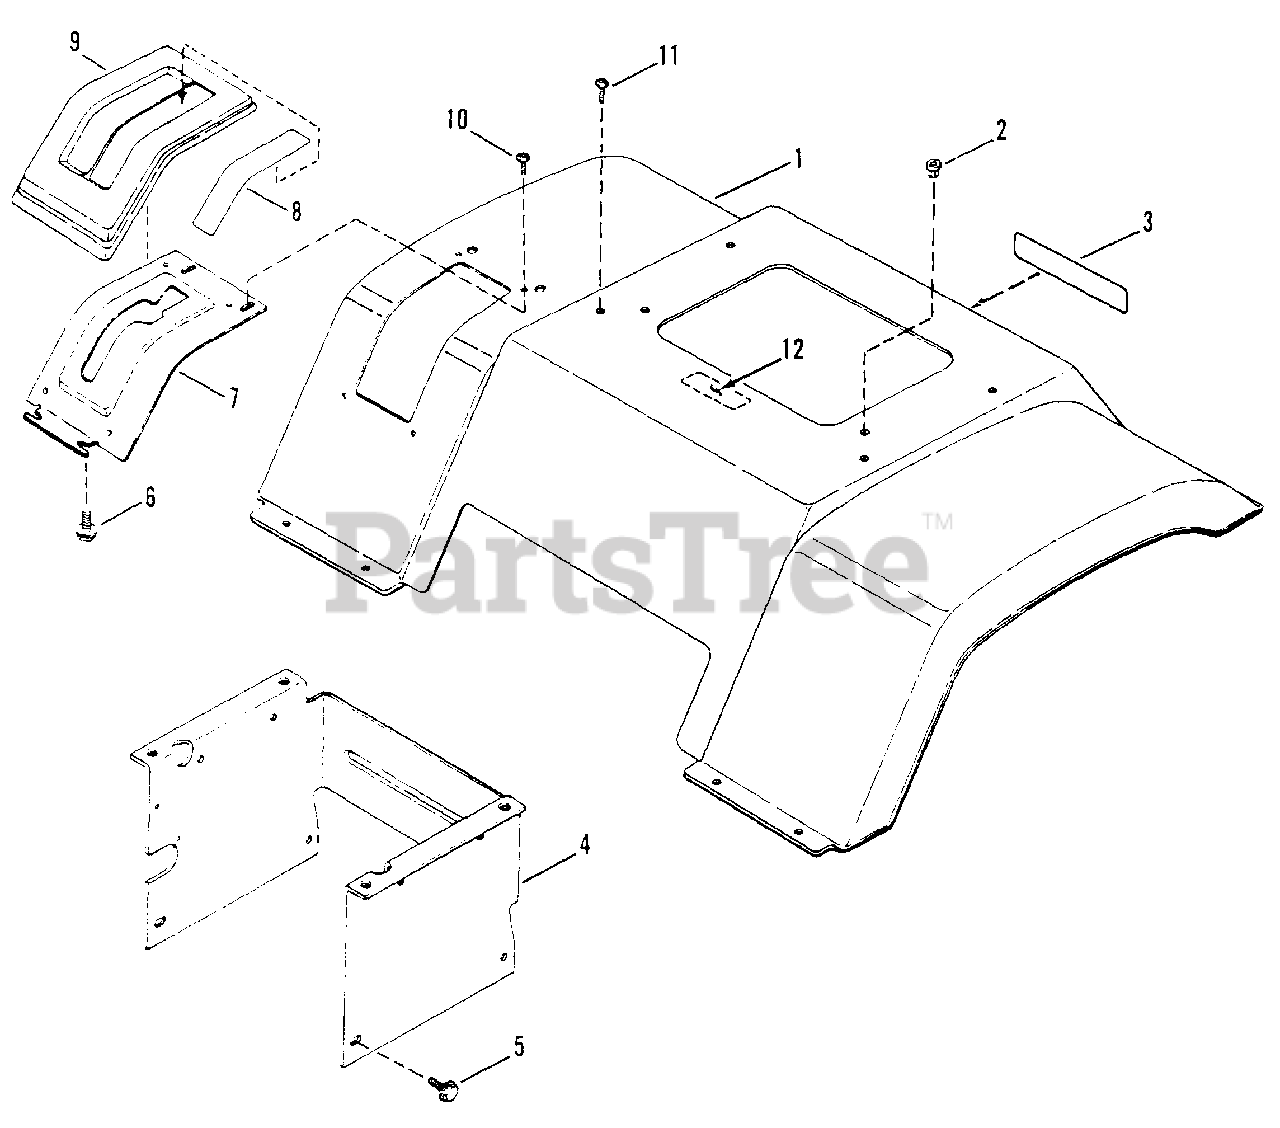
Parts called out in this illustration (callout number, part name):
1	PAN, Seat (Fender)
2	RIV-NUT, 5/16-18
3	DECAL-SNAPPER, 7.28" Molded Logo, White Letters & Stripe
3	DECAL-SNAPPER, 7.28" Molded Logo, Silver Letters, Teal Stripe
4	SUPPORT, Fender
5	SCREW, 5/16-18 x 5/8" Hex Washer Head, Self-Tapping
6	SCREW, #10-16 x 1/2" Hex Washer Head, Self-Tapping
7	DETENT, Gear Shift
8	DECAL, Shift Cover, 5 Speed
9	COVER, Shift
10	SCREW, 1/4-20 x 5/8" Truss Head, Torx
11	SCREW, 5/16-18 x 5/8" Truss Head, Torx
12	DECAL - CAUTION, Battery Location
